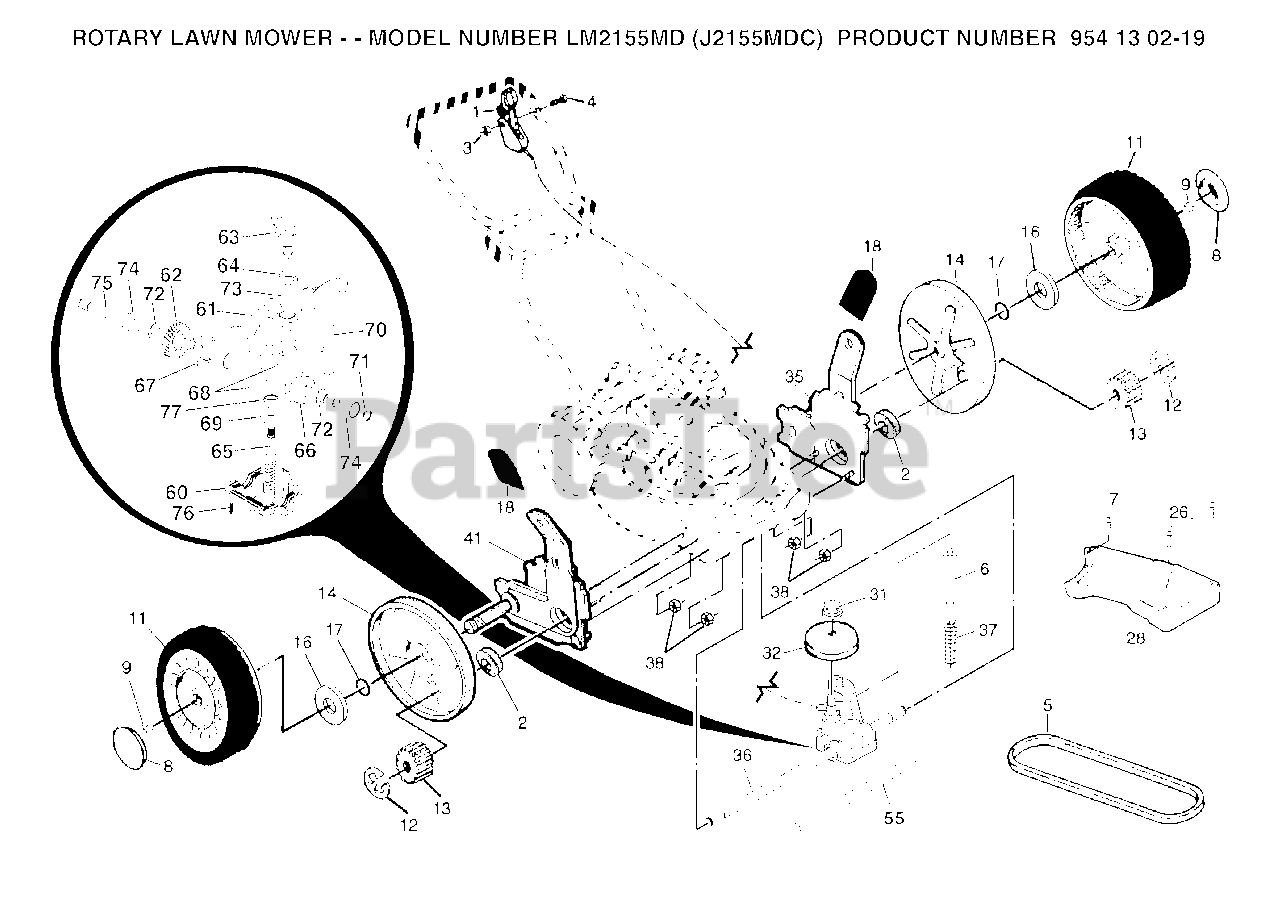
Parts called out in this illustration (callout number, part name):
1	DRIVE CONTROL 59.8 FWGD
5	BELT THERM .32
6	SPRING RETAINER
7	TAPPING SCREW
9	HEX FLANGE LOCKNT
11	WHEEL.8X2.RADIAL.GRAY
12	E-RING 7/16 RE
13	PINION GEAR
14	DUST COVER, WHEEL
16	WASHER FLUT
17	O-RING
18	SELECTOR KNOB
31	FLANGED LOCKNUT 3/8-16 ZINC
32	PULLEY, DRIVE
36	TRANSMISSION 22RD
37	SPRING.EXTENSION
38	LOCKNUT
55	DRV SHAFT TUBE PM
60	LOWER CASE
61	UPPER CASE
62	GEAR.27.TEETH.WALK.MOWER
63	LEVER, CLUTCH
64	SPRING, RETURN
65	SHAFT, INPUT
66	DOG, MOVABLE
67	DOG, FIXED
68	WIRE, FORMED
70	FORK, SHIFT
71	SEAL.OUTPUT.SHAFT
73	SEAL, CASE
77	SEAL INPUT SHAFT
